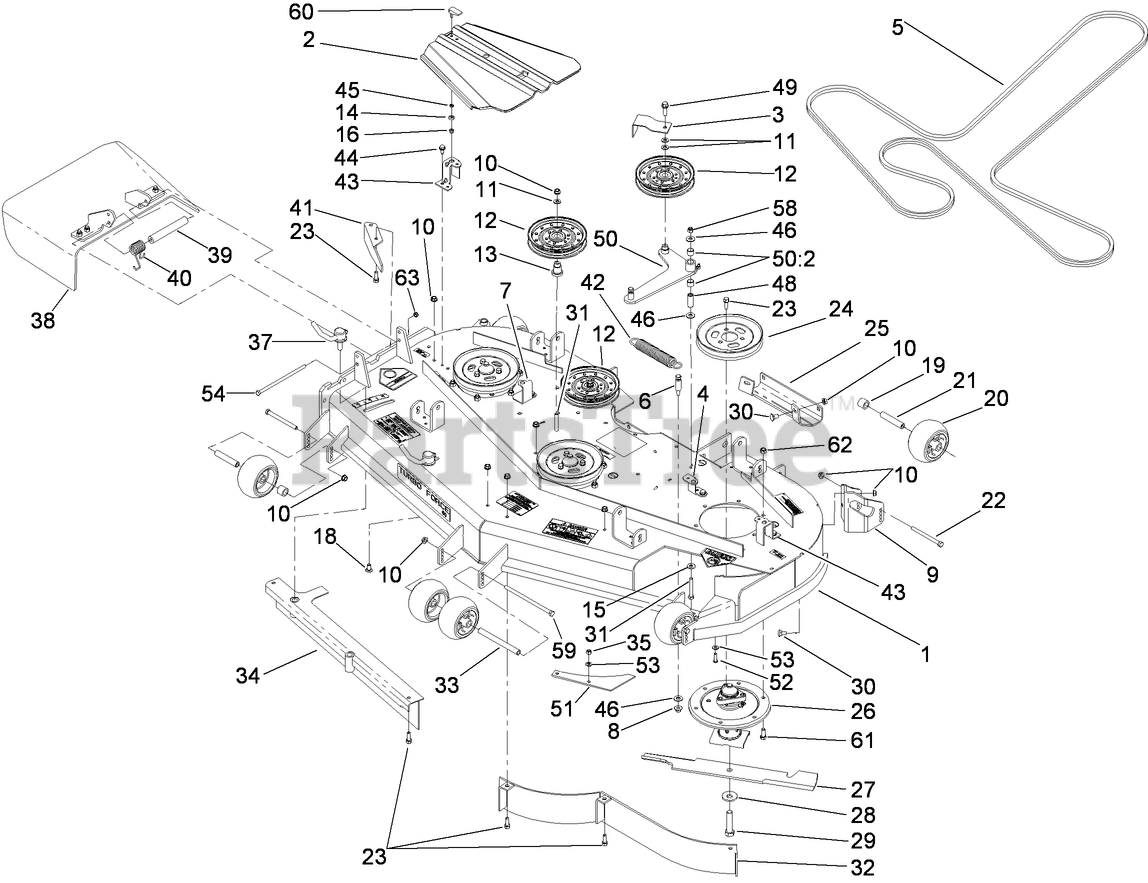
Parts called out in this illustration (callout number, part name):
1	DECK DECAL ASM
2	COVER-BELT
3	GUIDE-BELT
4	BRACKET-COVER, TALL
5	BELT-V
6	PIN-THREADED, SPRING ANCHOR
7	BRACKET-COVER
8	NUT-HF
9	MOUNT-WHEEL, LH
10	NUT-HHF, WHIZ
11	WASHER-FLAT
12	Idler-Flat
13	MOUNT-PULLEY
14	BUSHING-LATCH, SWELL
15	WASHER-BELLEVILLE
16	NUT-LOCK, HH
18	SCREW-CARR
19	TUBE-SPACER
20	ROLLER-SCALP, ANTI
21	TUBE-SPANNER
22	SCREW-HH
23	SCREW-HWH
24	Pulley
25	Plate-Skid
26	SPINDLE ASM
27	BLADE-HI FLOW
28	Washer-Blade Bolt, Heavy
29	Screw-Cap
30	SCREW-CARR
31	SCREW-HH
33	SPACER-WHEEL
35	NUT-LOCK, NI
37	LEVER ASM
38	RUBBER DEFLECTOR ASM
39	SPACER
40	SPRING-TORSION
41	BAFFLE-DISCHARGE
42	SPRING-EXTENSION
43	BRACKET-COVER
44	SCREW-HWHTF
45	WASHER
46	WASHER-FLAT
48	BUSHING
49	SCREW-HHF
50	DECK IDLER ARM ASM
50:2	SLEEVE-BEARING
51	PLATE-TURBO
52	SCREW-HSBH
53	WASHER-SPRING
54	SCREW-HH
58	NUT-LOCK, NI
59	SCREW-HH
60	HANDLE-LATCH, SWELL
61	SCREW-HH
62	NUT-LOCK, NI
63	NUT-LOCK, NI
